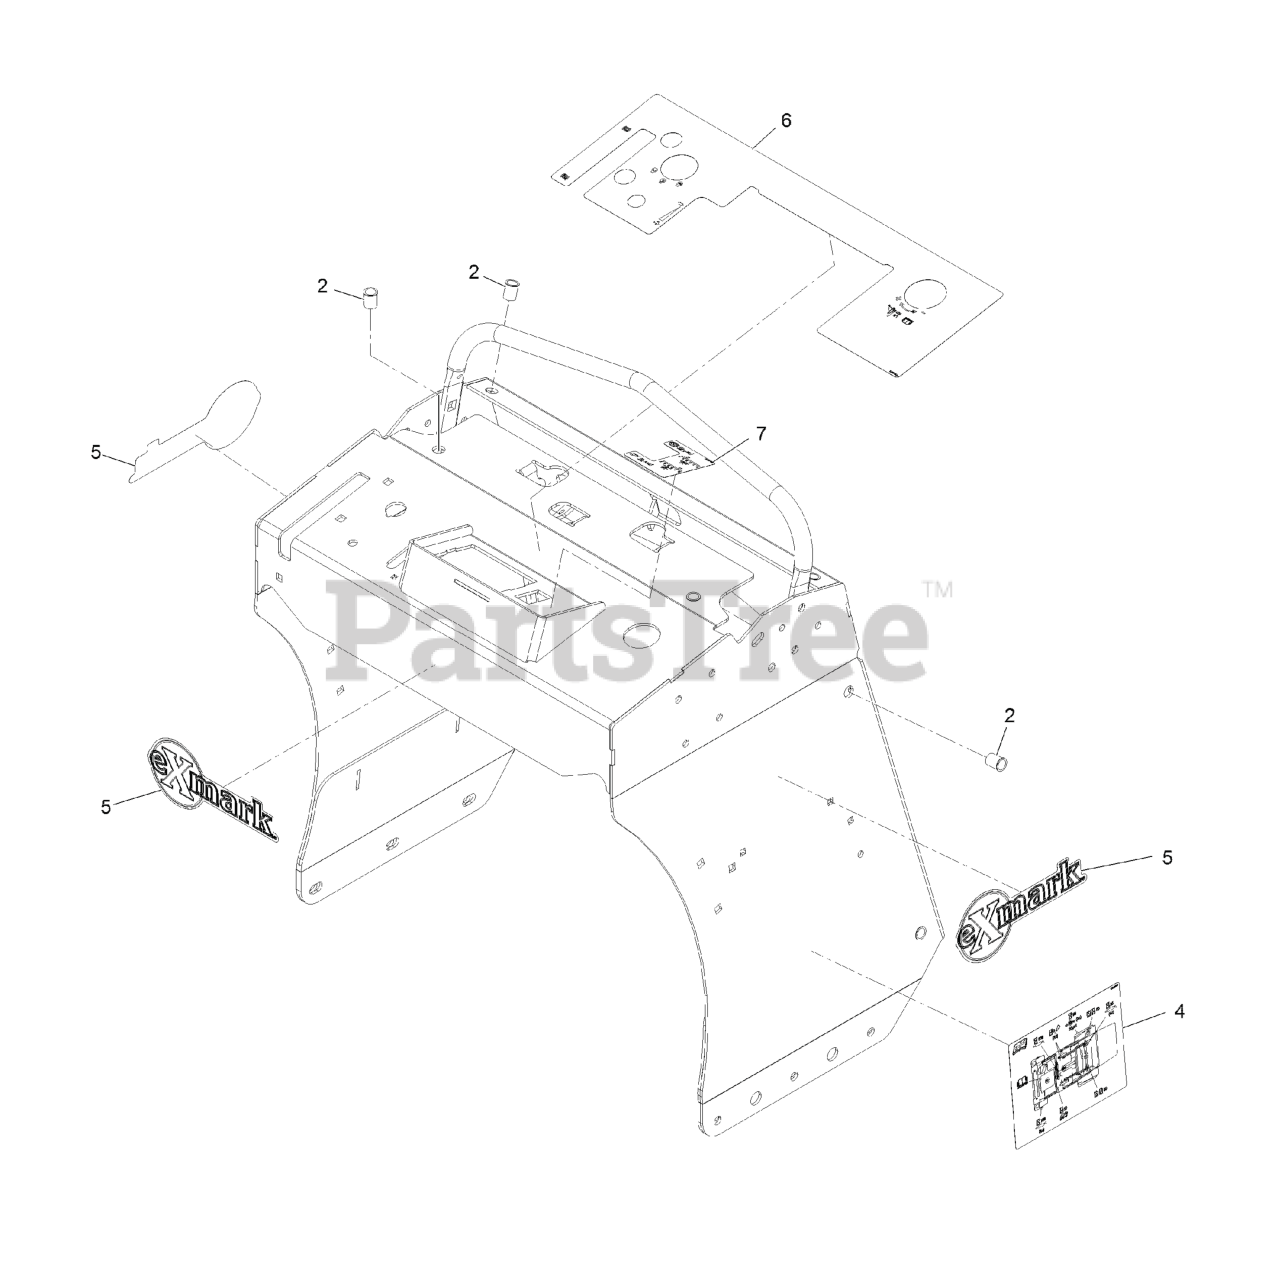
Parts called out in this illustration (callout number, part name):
2	NUT-CLINCH
4	DECAL-AID, SERVICE
5	DECAL, EXMARK LOGO
6	DECAL-PANEL, CONTROL
7	DECAL-CONTROL, TINE
